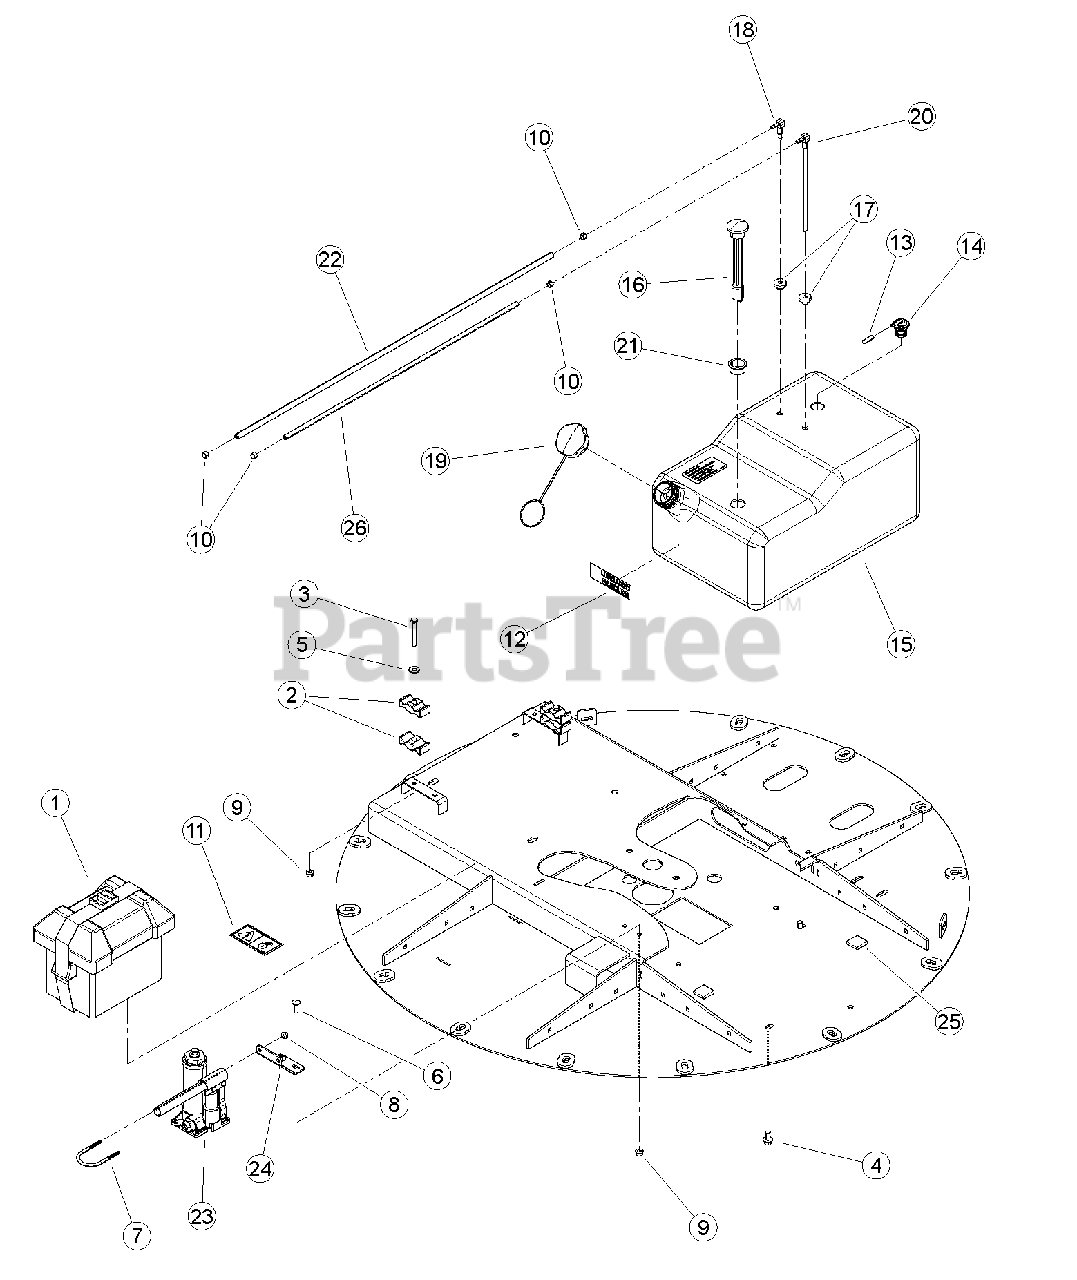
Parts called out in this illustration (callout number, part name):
1	BOX, SMALL BATTERY
2	CLAMP, PLASTIC HOSE
3	BOLT, 5/16 X 2-1/2 G5 HEX CAP ZP
4	BOLT, 3/8 X 3/4 FLANGE NC
5	WASHER, 5/16" FLAT ZP
6	BOLT, 5/16 X 1" GR5 CRG ZP
7	U-BOLT, 1/4 X 1-1/2 PIPE
8	NUT, 1/4-20 NYLOCK-FLANGE
9	NUT, 5/16-18 NYLOCK-FLANGE
10	CLAMP, 15/32 SPRING
11	DECAL, LOCK
12	DECAL, UNLEADED GASOLINE
13	CAP, EPDM BLACK .223 ID X 1.0 LG X .06 WALL
14	VALVE, ROLL OVER
15	TANK, ROTOMOLDED FUEL
16	GAUGE, FUEL LEVEL KELCH 100
17	GROMMET, TANK FITTING
18	FITTING, TANK VENT
19	CAP, FUEL TANK VENTED
20	FITTING, TANK FUEL PICK-UP TUBE
21	GROMMET, KELCH 100 GAUGE
22	HOSE, 38" FUEL LINE
23	JACK, HYDRAULIC 2 TON
24	PLATE, JACK MOUNT
25	PAD, FOAM FUEL TANK DAMPER
26	HOSE, 28 INCH FUEL LINE 1/4"
